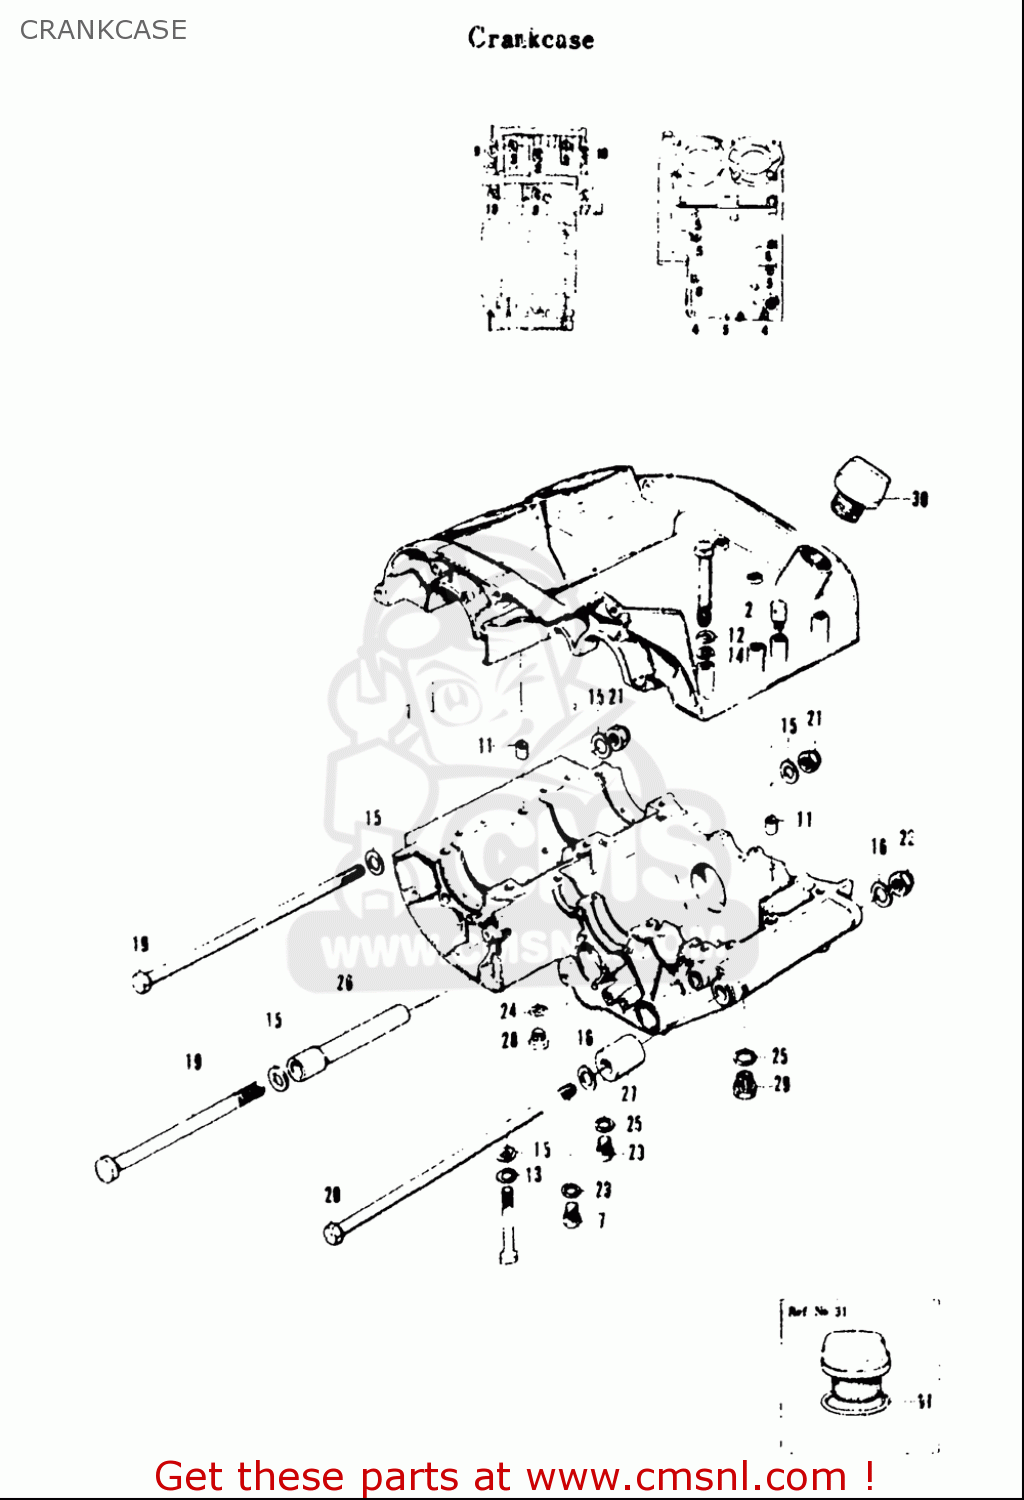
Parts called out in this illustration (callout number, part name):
2	PLUG,T/M BREATHER
3	BOLT
4	BOLT
5	BOLT
6	BOLT(6X60)
8	BOLT
9	BOLT
10	BOLT
11	PIN
12	WASHER,LOCK
13	WASHER,LOCK
14	WASHER
15	WASHER
16	WASHER
17	BOLT 8X100
21	NUT
23	GASKET(8.2X14X1) (NAS)
24	GASKET(10X14X3.6) (NAS)
25	GASKET(14X19.2X2) (NAS)
28	PLUG
29	PLUG(MAGNETO)
30	PLUG SET
31	O RING(D:2.4,ID:21.8)
